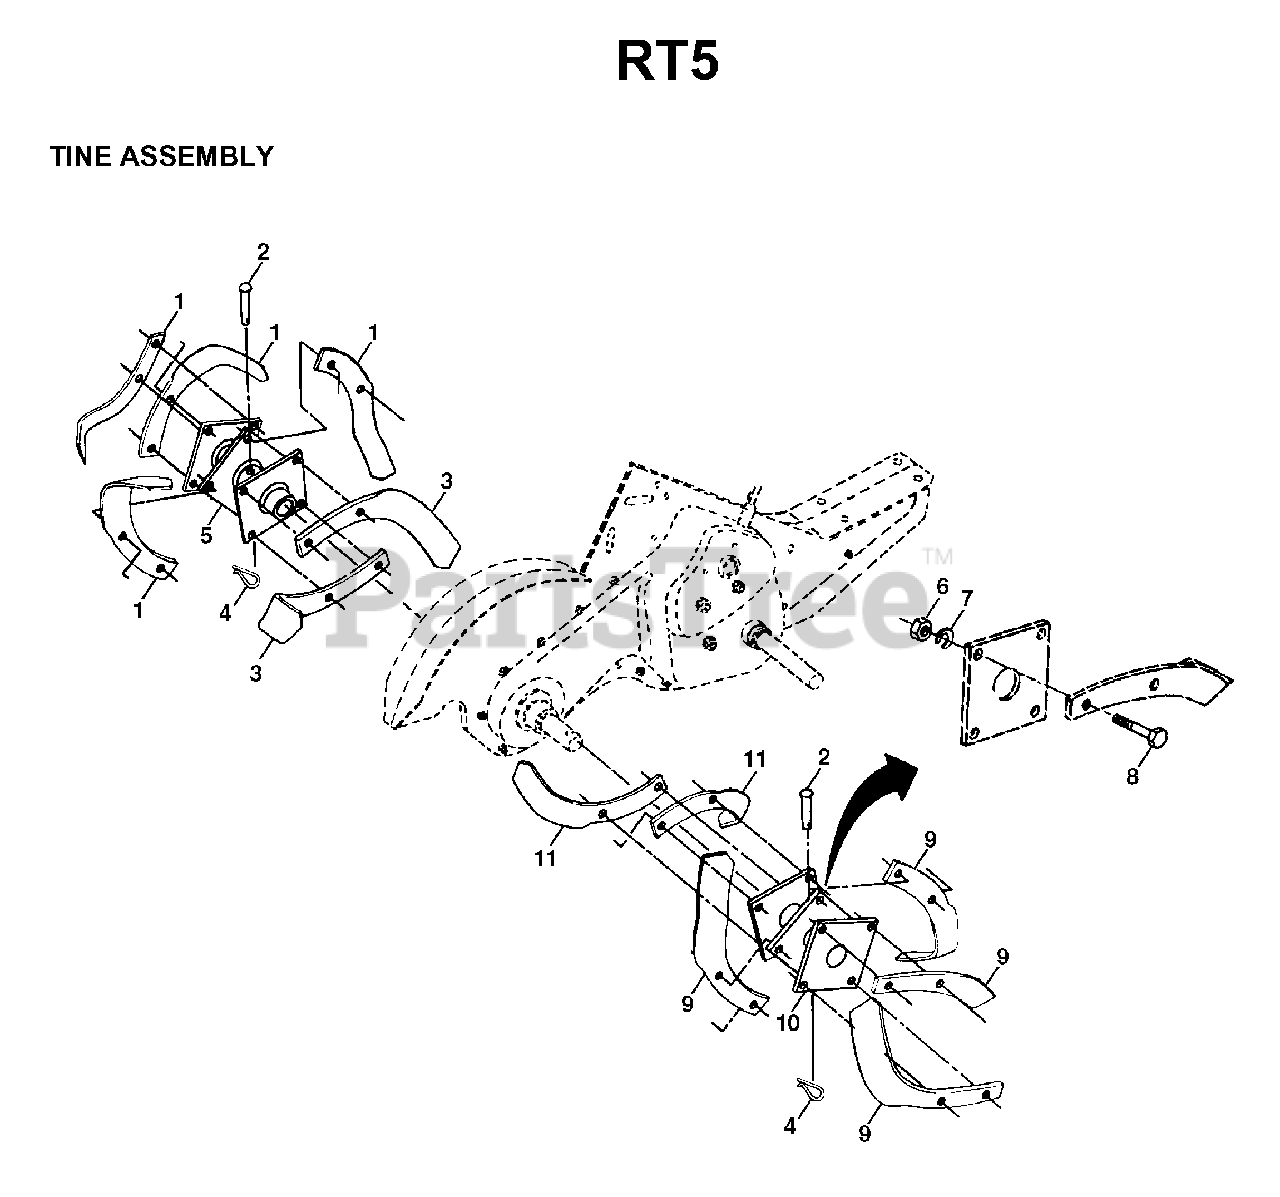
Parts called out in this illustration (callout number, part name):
1	TINE TI
2	CLEVIS PIN
3	TINE.LH.12"
4	SPRING RETAINER
5	HUB & PLATE ASM LH
6	NUT
7	WASHER, LOCK 3/8
8	BOLT.HEX.001X20.37-24X1.ZINC
9	TINE TI
10	HUB & PLATE ASM RH
11	TINE.RH.12"(72R)
